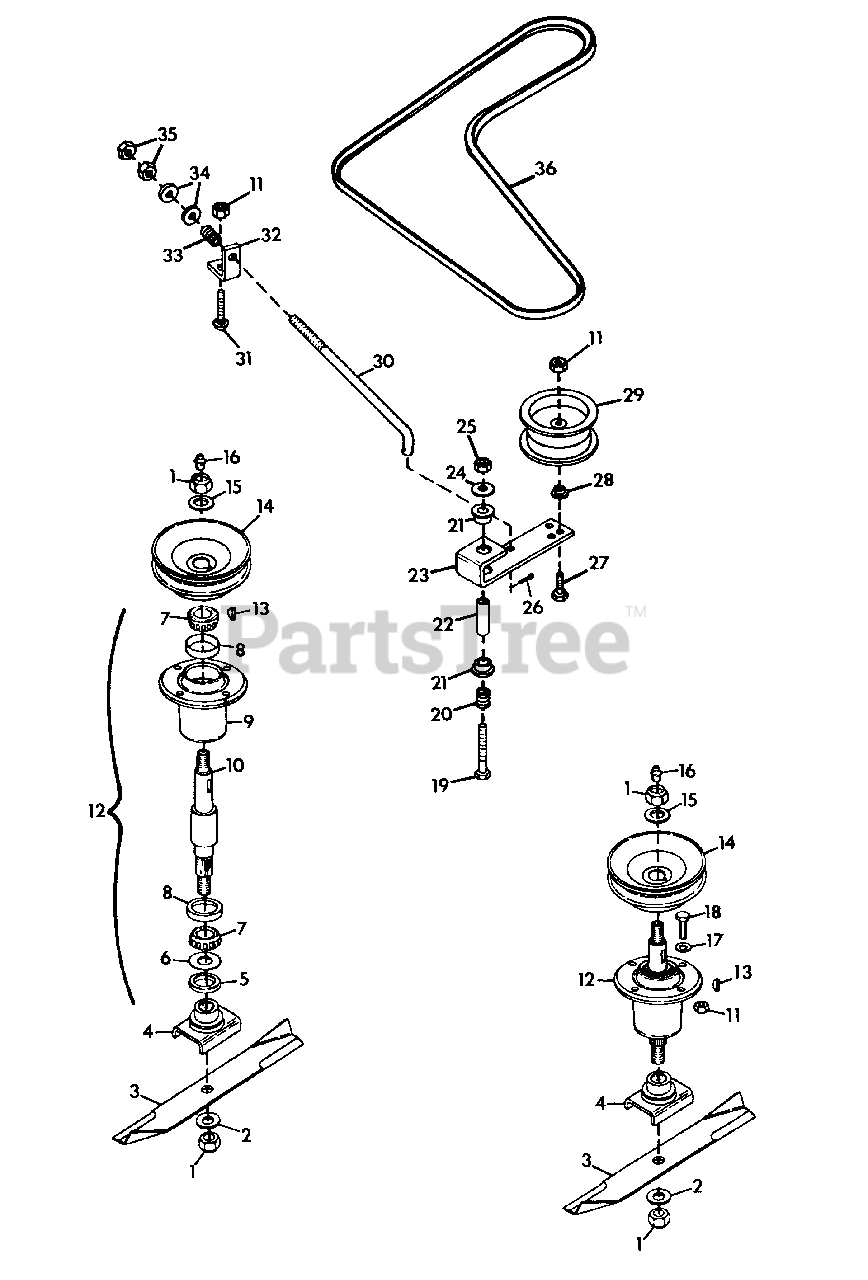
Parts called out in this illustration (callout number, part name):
1	NUT, LOCK 5/8-11
2	WASHER, FLAT .656X1.312X.095
3	BLADE
4	CRADLE, BLADE
5	SEAL, STEEL
6	WASHER, FLAT .975X1.970X.030
7	BEARING, CONE
8	BEARING, CUP
9	HOUSING, BEARING
10	SHAFT, SPINDLE
11	NUT, LOCK 3/8-16
12	ASSEMBLY, SPINDLE
13	KEY, WOODRUFF 1/4X1 HARD
14	SHEAVE, SPINDLE
15	WASHER, FLAT .687X1.312X.122
16	FITTING, LUBE 1/8 NPT
17	WASHER, FLAT .438X1.00X.083
18	BOLT, HEX 3/8-16X1.250
19	BOLT, HEX 1/2-13X3.25
20	SPRING, COMPRESSION 1X.80X36 LB/N
21	BUSHING, NYLON .760X1.00X.600
22	SPACER
23	ARM, IDLER PIVOT
24	WASHER, FLAT .531X1.250X.100
25	NUT, LOCK 1/2-13
26	PIN, COTTER .09X.75
27	BOLT, HEX 3/8-16X2.25
28	BUSHING
29	PULLEY, IDLER
30	ROD, IDLER
31	BOLT, 3/8-16X1.00 RD HD SQ NK
32	BRACKET, BELT TENSIONER
33	SPRING, COMPRESSION 1.00X.78
34	WASHER, FLAT .406X.812X.065
35	NUT, HEX 3/8-24
36	BELT, PRO-40 MOWER
